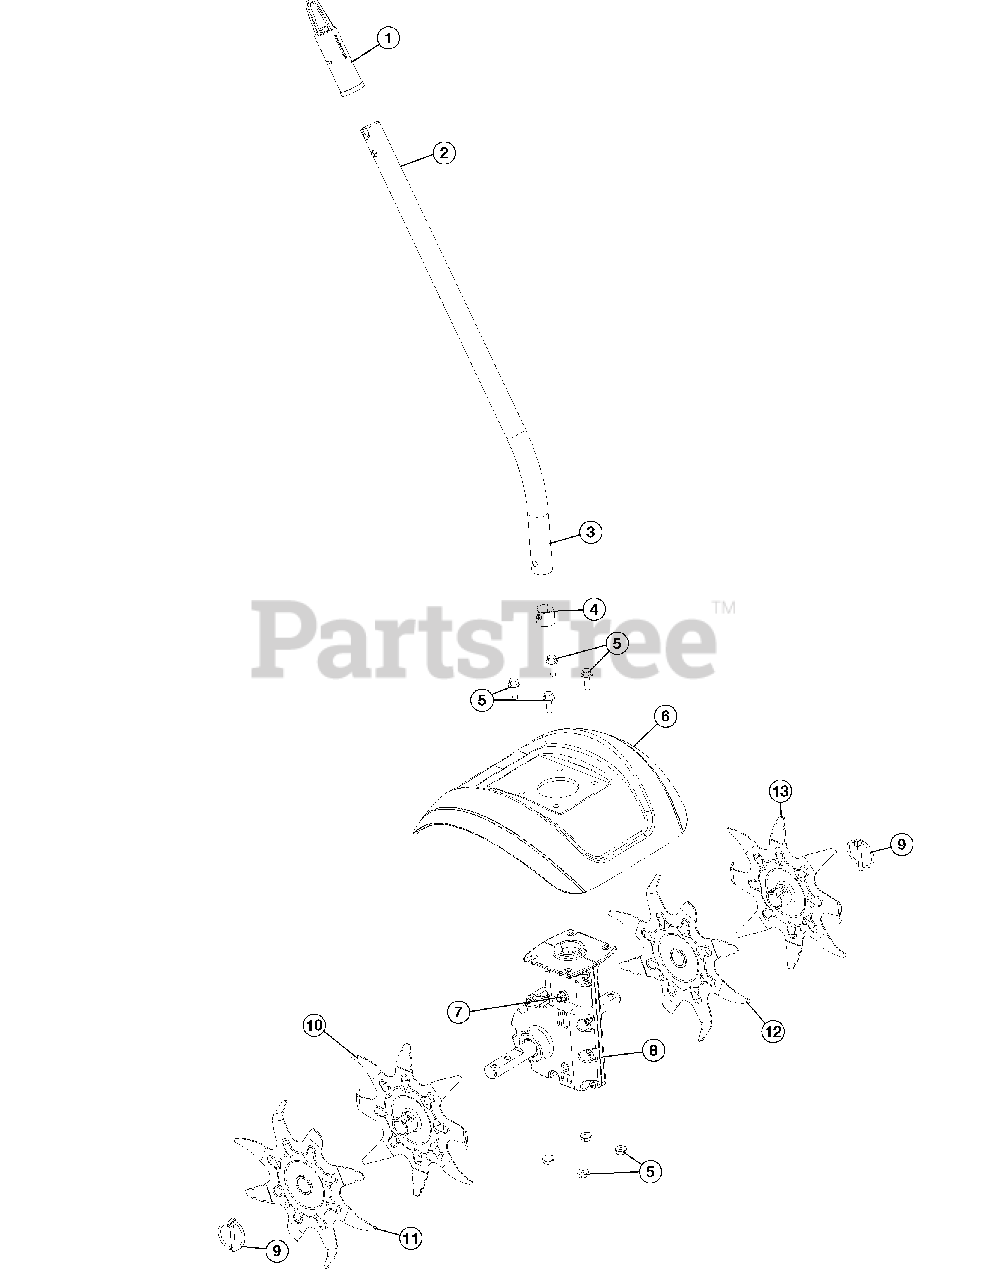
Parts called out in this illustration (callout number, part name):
1	Accessory Hanger
2	Drive Shaft Housing Assembly
3	Flexible Drive Shaft
4	Retainer Sleeve
5	Mounting Hardware Set
6	Tine Shield
8	Gear Box Assembly
10	Right Inner Tine
11	Right Outer Tine
12	Left Inner Tine
13	Left Outer Tine
